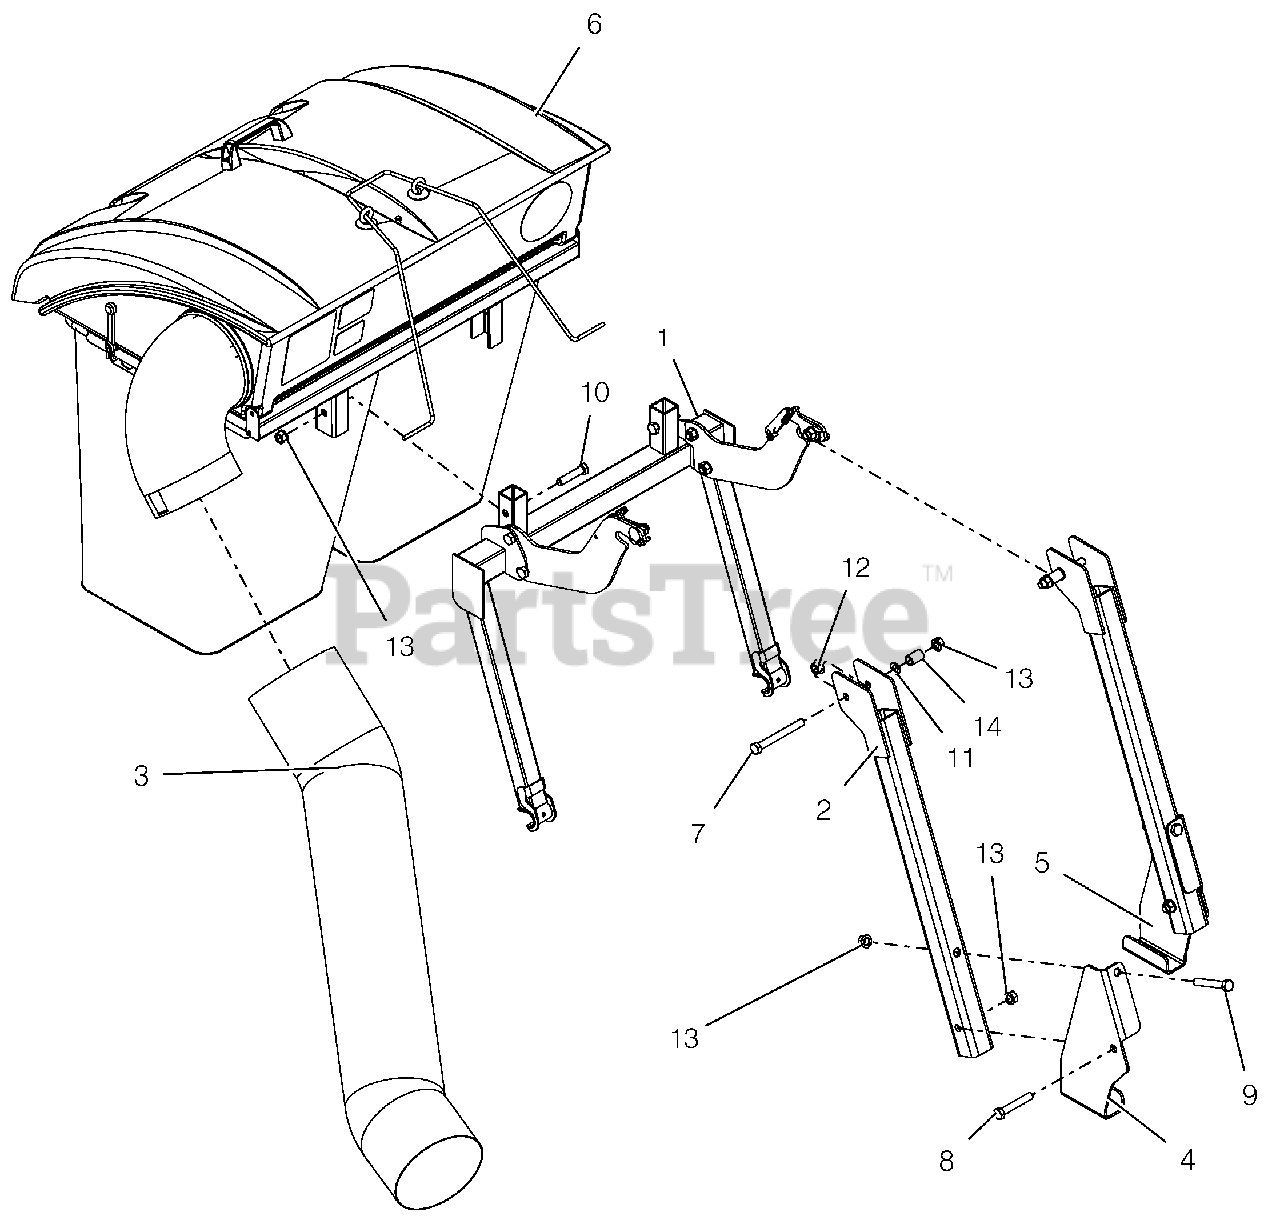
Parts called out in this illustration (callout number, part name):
1	WLDMT, BAGGER POST HD BLACK
2	WLDMT, BAGGER FRONT MOUNT
3	HOSE, FLEXIBLE-47"
4	BRKT, ROPS SUPPORT - RH
5	BRKT, ROPS SUPPORT -LH
6	BAGGER, PECO 2-BAG MID (A2116)
7	@BLT-HEX .5-13-4.5GR8 FULL THD
8	@BLT-HEX .50-13X3.00 GR5 YWZC
9	@BLT-HEX .50-13X3.25 GR5 YWZC
10	@BLT-HEX .50-13X2.25 GR5 YWZC
11	WSHR-FL-STL .505X.880X.072 YWZ
12	NUT-SPNLK-FLG .50-13 YWZC
13	@NUT-LK-TOP-FLG .50-13 YWZC
14	SPACER .510 X .75 X 1.1485
